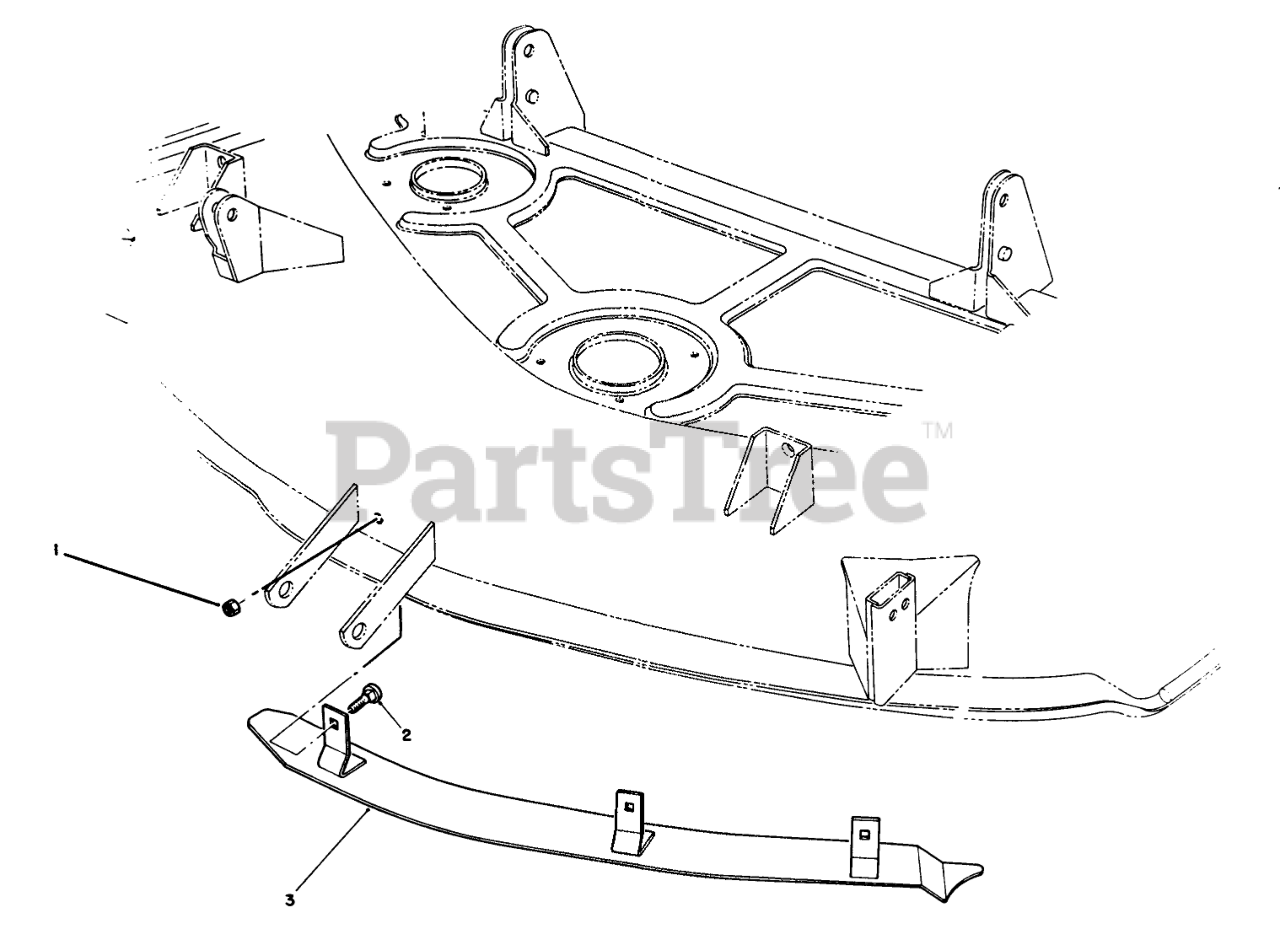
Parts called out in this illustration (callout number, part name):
1	NUT-LOCK, NI
2	SCREW-CARR
3	Baffle W.A.
